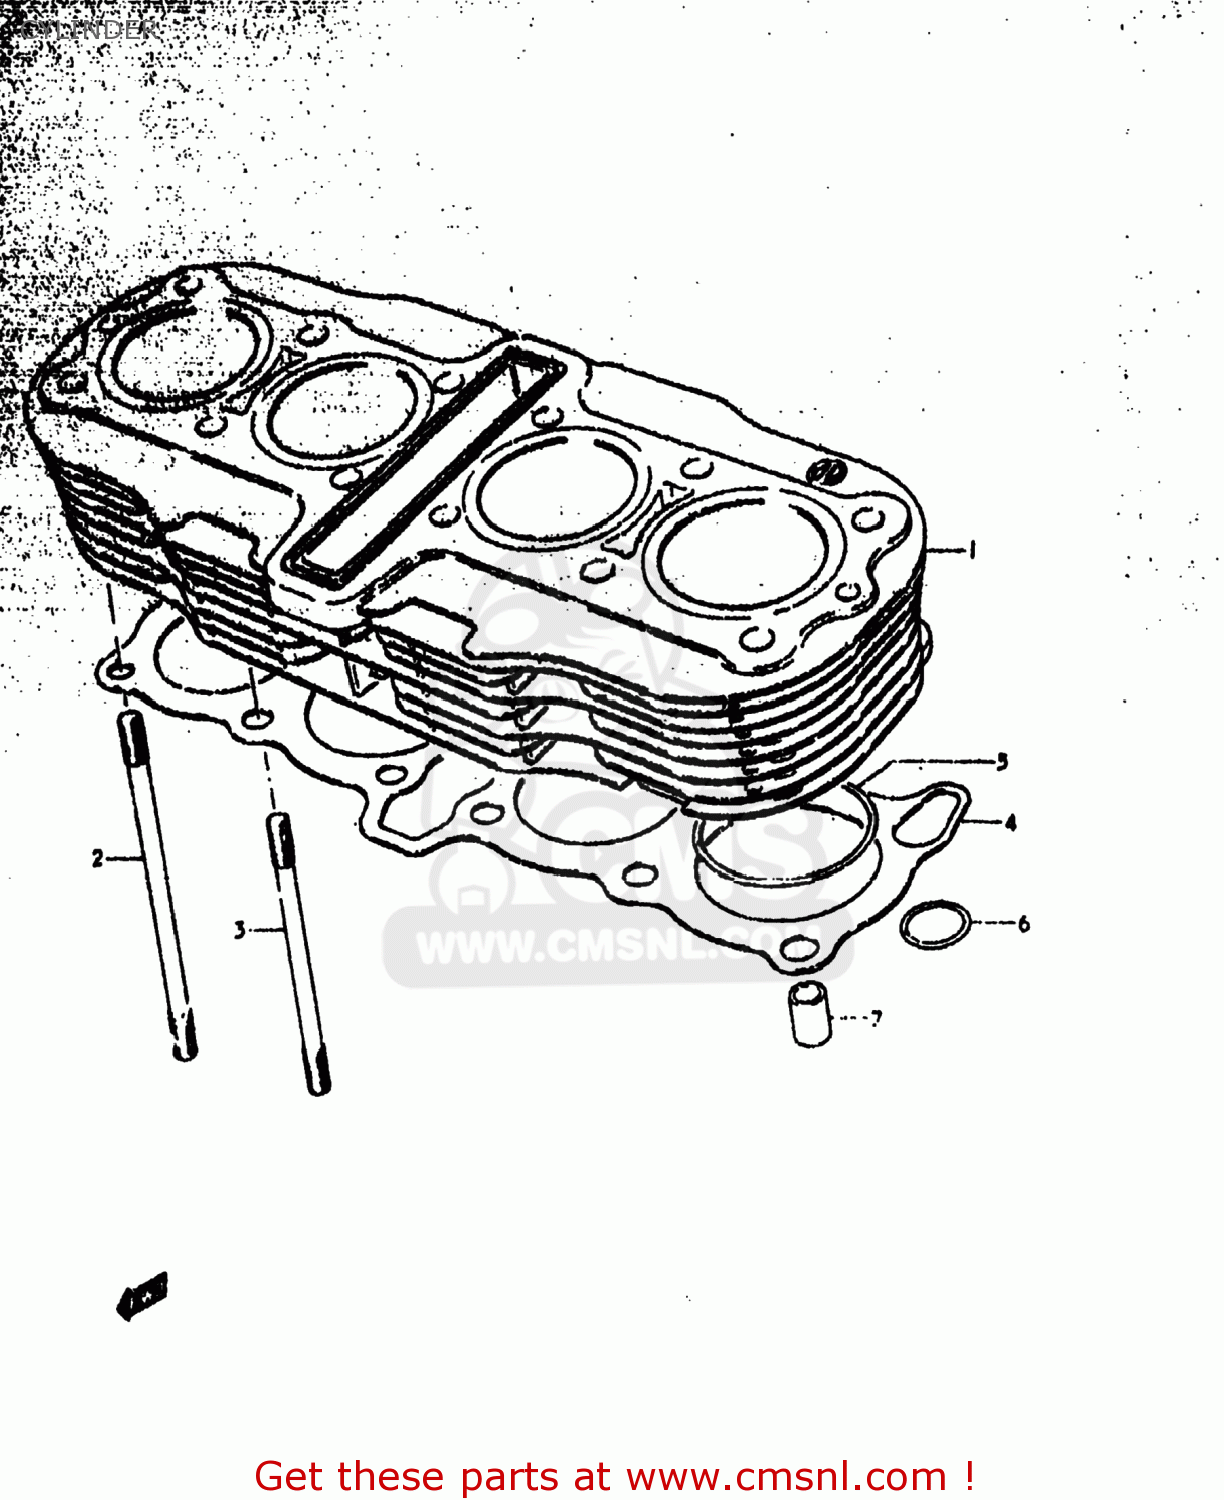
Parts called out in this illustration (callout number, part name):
1	CYLINDER
2	STUD
3	STUD
4	GASKET,CYLINDER (MCA)
5	O RING(D:2,ID:74)
6	O RING(D:3.05)
7	PIN
